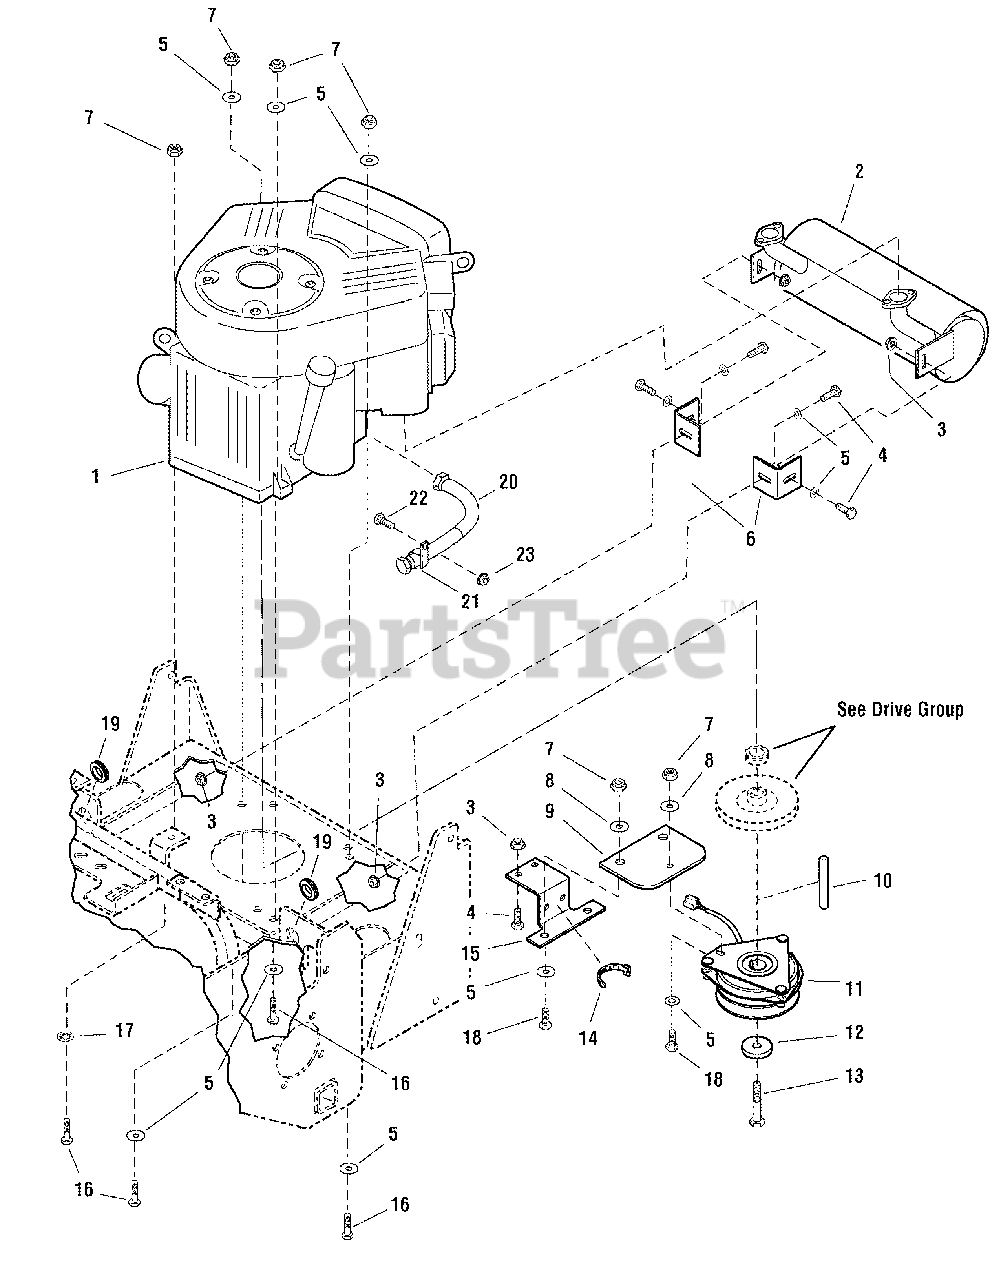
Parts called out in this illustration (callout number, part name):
3	NUT, Hex Serrated Flange, 5/16-18
4	CAPSCREW, Hex Head, 5/16-18 X 3/4
5	WASHER, SAE, 5/16
6	BRACKET, Muffler Support, Orange
6	BRACKET, Muffler Support, Red
7	NUT, Hex Nylon Lock, 5/16-18
8	WASHER, 3/8 Fender
9	PAD, Clutch Anchor
10	KEY, 1/4 Square X 2-1/4
11	CLUTCH, Electric
12	SPACER, .45 X 1.62 X .37
13	BOLT, CRANKSHAFT, 7/16-20 X 3-1/4"
15	CLUTCH ANCHOR, Orange
15	CLUTCH ANCHOR, Red
16	CAPSCREW, Hex Head, 5/16-18 X 1-3/4
17	WASHER, 5/16 Internal Tooth Lock
18	CAPSCREW, Hex Head, 5/16-18 X 1
19	GROMMET, 3/4"
20	HOSE, Oil Drain
21	CLAMP, Vinyl Insulated
22	BOLT, 1/4-20 x 3/4
23	NUT, 1/4-20 Hex, Serrated Flange
